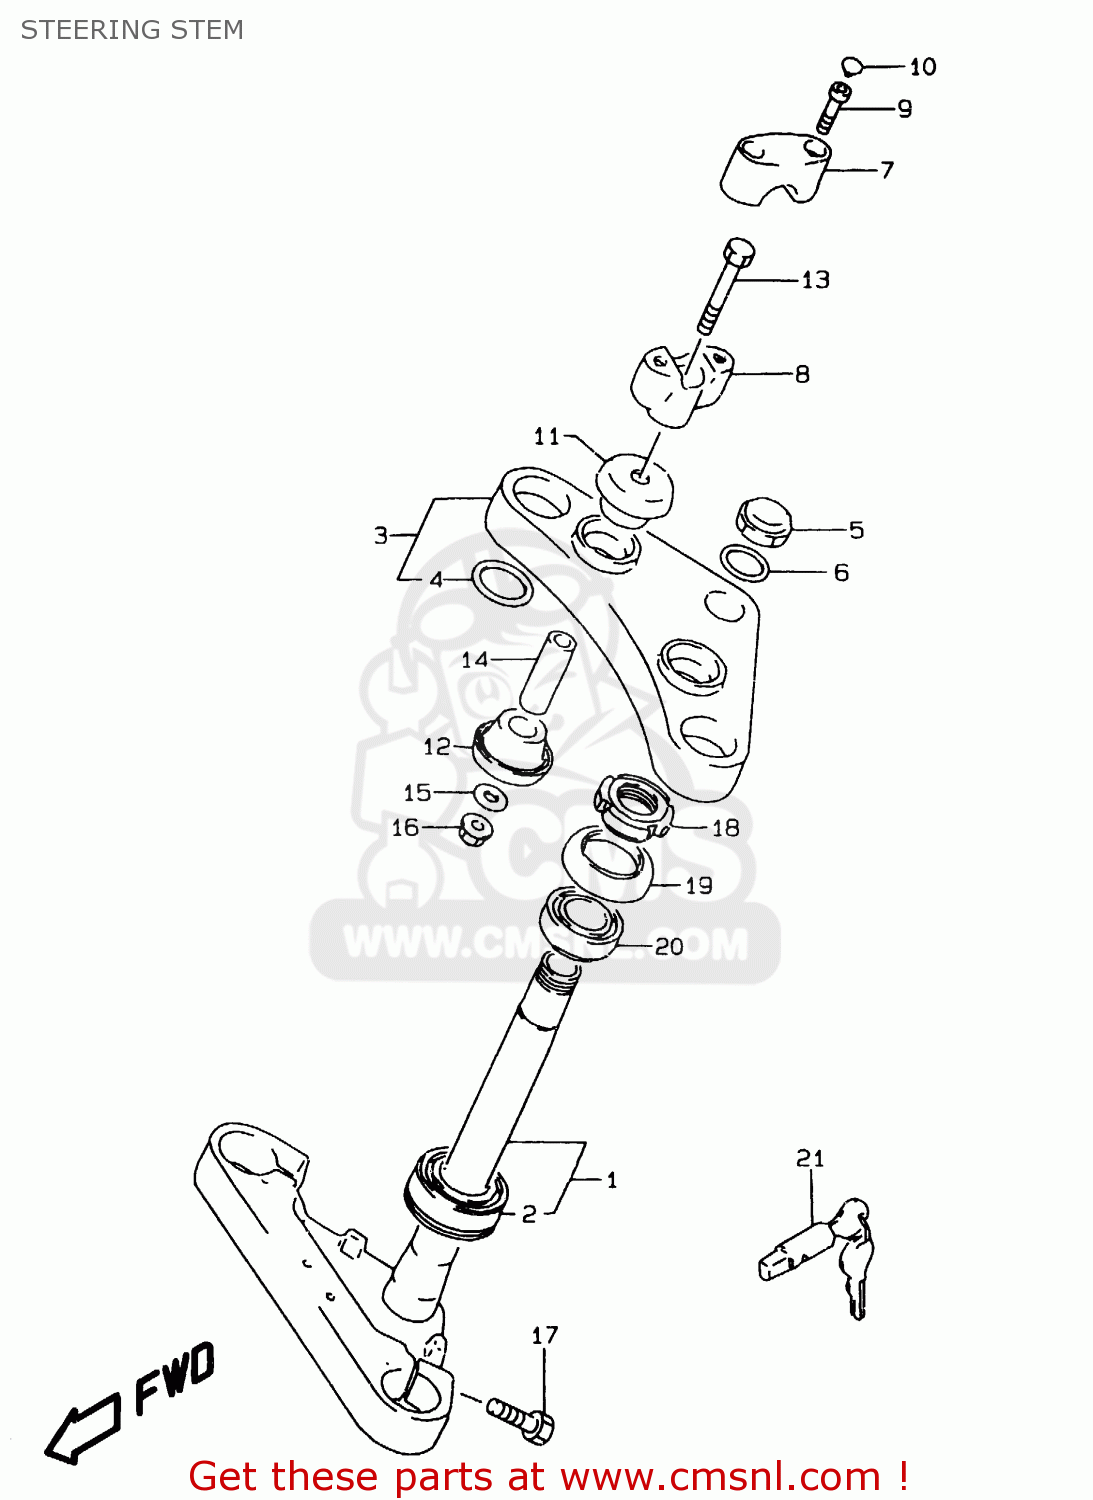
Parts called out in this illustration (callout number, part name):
1	STEM,STEERING
2	BEARING(30X55X17)
3	HEAD,STEERING STEM
4	WASHER,STEM HEAD,LOWER
5	NUT,CAP
6	WASHER(22.5X32X1.6)
7	HOLDER,HANDLE UPR
8	HOLDER,HANDLE LWR
9	BOLT
10	CAP(OD:14.5)
11	CUSHION,UPR
12	CUSHION,LWR
13	BOLT,DAMPER(10X77)
14	SPACER(10.2X14X46)
15	WASHER
16	NUT
17	BOLT
18	NUT,STEERING STEM(25X44X10)
19	SEAL,STEERING UPR DUST
20	BEARING(25X47X15)
21	LOCK ASSEMBLY,STEERING (NEI
